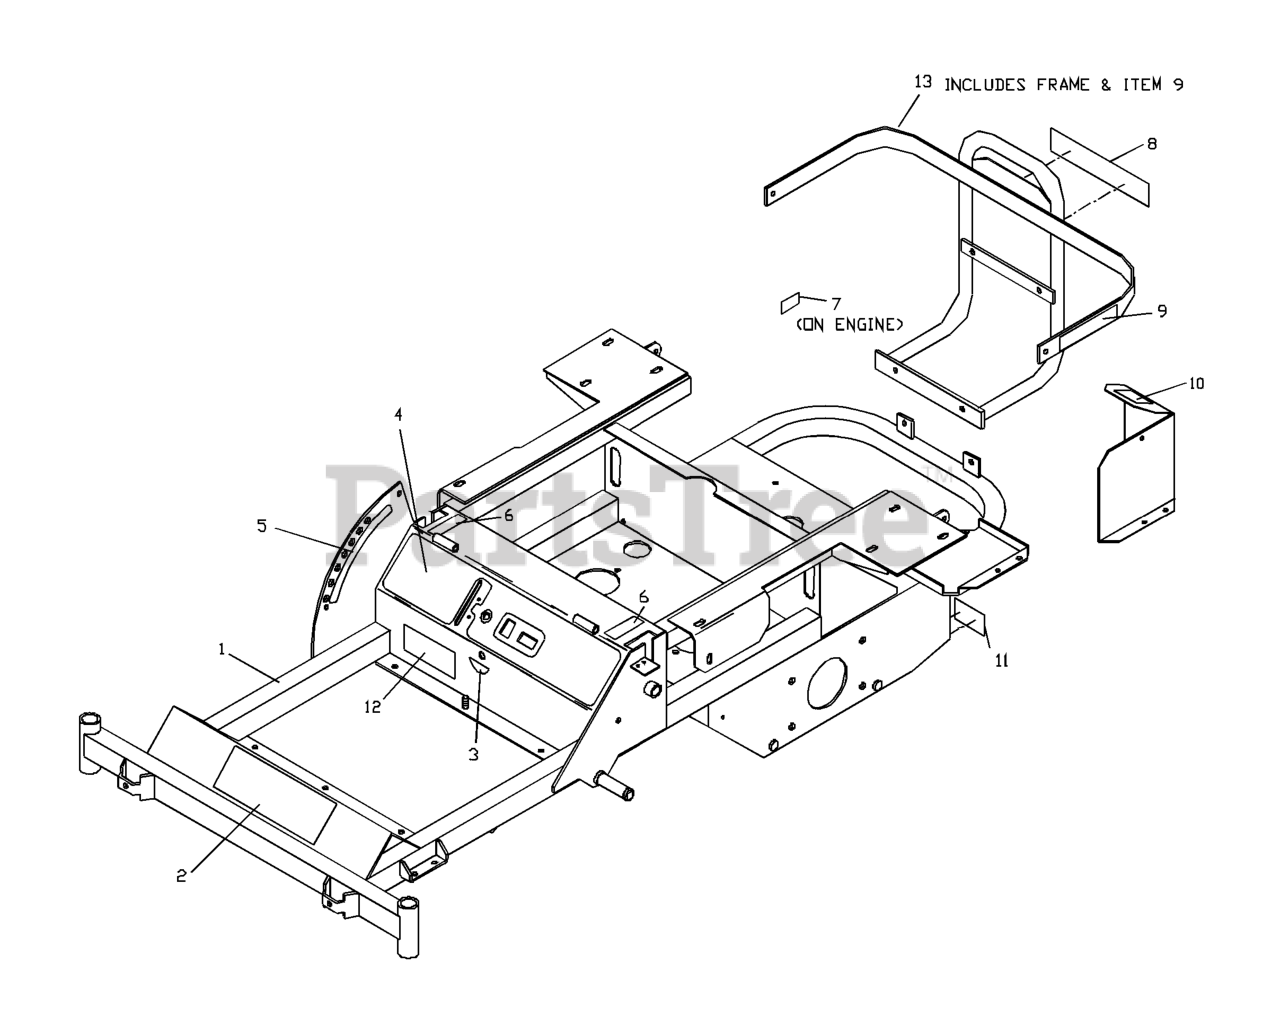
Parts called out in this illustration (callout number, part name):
1	FRAME W/DECALS KOHLER
1	FRAME W/DECALS KAWASAKI
2	DECAL, HUSQVARNA 15.5"
3	DECAL, FUEL VALVE
4	CONSOLE DECAL
4	DECAL, CONSOLE KOHLE
5	DECAL, LOCATOR
6	DECAL, MOTION CONTROL
7	DECAL, EXHAUST
8	DECAL, HUSQVARNA LOGO 9.25"
9	DECAL, BATTERY
10	DECAL, PROP. 65
11	DECAL, DANGER
12	DECAL, NASCAR
13	ENGINE GUARD W/DECAL
